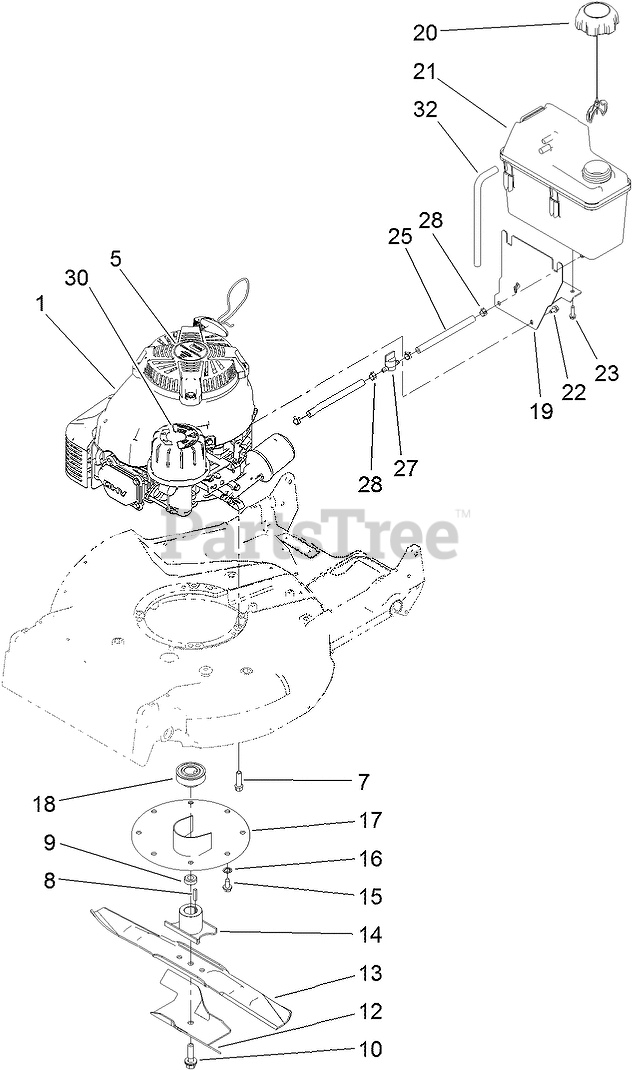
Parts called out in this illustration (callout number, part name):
1	ENGINE-KAWASAKI, FJ180V-AM08-M
7	SCREW-TAPTITE
8	KEY-SQUARE
9	Spacer-Retainer, Blade
10	BOLT-BLADE
12	STIFFENER-BLADE
13	BLADE-21 INCH
14	RETAINER-BLADE
15	SCREW-HWHTF
16	WASHER-LOCK, INTERNAL
17	CRANKSHAFT PROTECTOR ASM
18	PULLEY-DRIVER
19	MOUNT-TANK
20	CAP-RATCHET, TETHERED
21	TANK-FUEL
22	SCREW-HWH
23	SCREW-HWH
25	HOSE-FUEL
27	VALVE-FUEL
28	CLAMP-HOSE
32	HOSE-VENT, CANISTER
